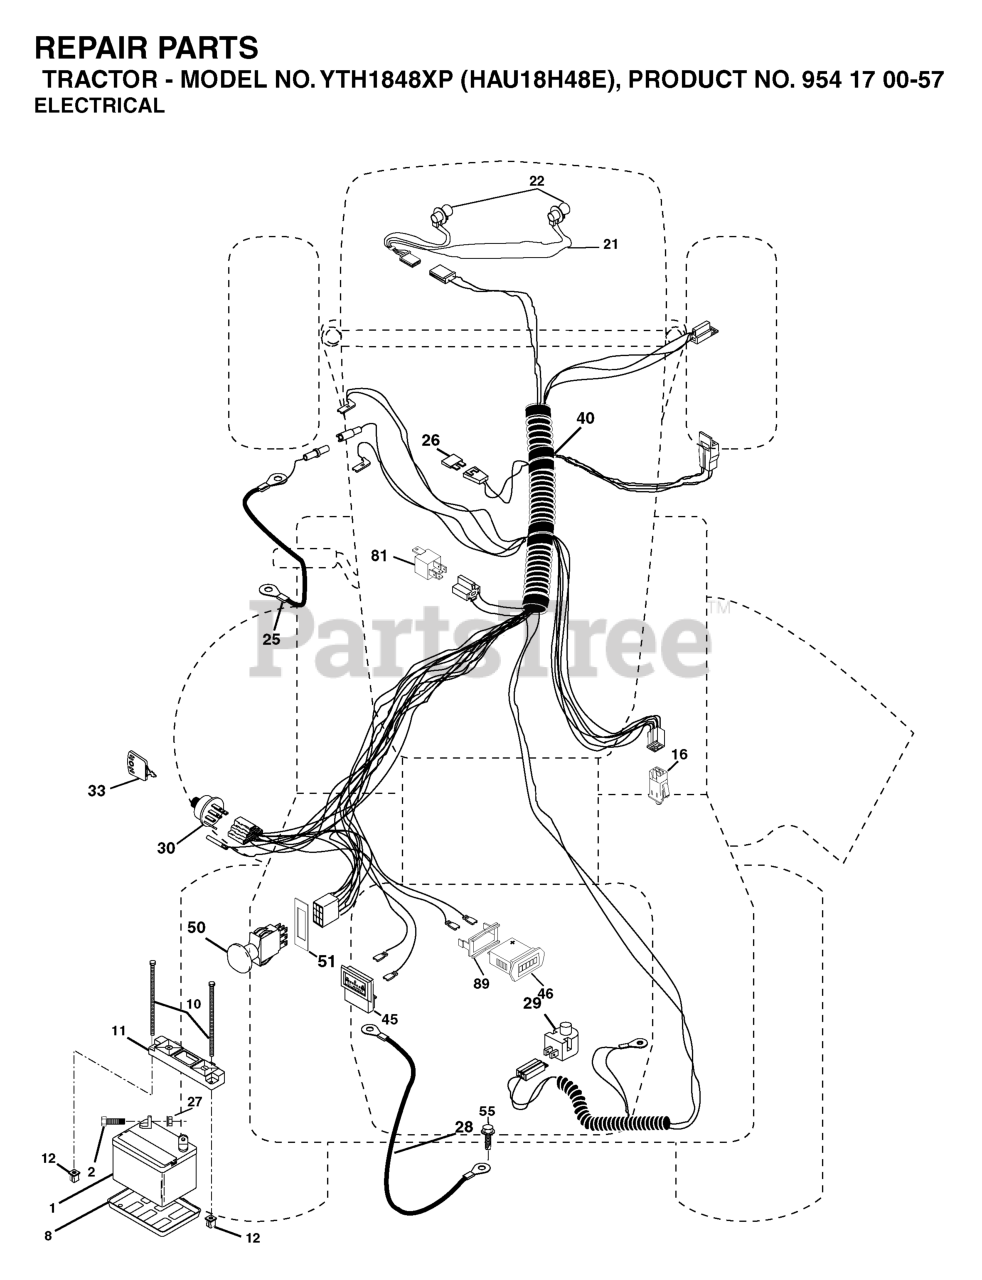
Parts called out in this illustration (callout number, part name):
1	BATTERY 12V .35 AMP
2	BOLT.HEX.1/4.X.3/4.DICHROMATE
8	BATTERY TRAY T
10	BOLT 1/4-20 X 7.5
11	BATTERY HOLDDOWN FRONT MOUNT
12	NUT, PUSH NYLON 1/4" BATTERY
16	SWITCH INTERLOOK PUSH-IN
21	HARNESS.ASM.LIGHT WSL
24	BATTERY CABLE GT
25	CABLE BATTERY 6 GA 22" W/16W
26	FUSE 20AMP
27	NUT
28	CABLE GROUND 6 GA 21" 90T BLK
29	PLUNGER SWITCH (COLOR:OLIVE)
30	IGNITION SWITCH
33	KEY MLD GEN DELTA
40	HARNESS IGN.
41	BOLT
42	TERMINAL COVER
43	SOLENOID
46	HOUR METER
50	RP.PTO.SWITCH.8 TERMINAL.BLACK
51	FRAME RETAINING RING
55	Screw 5/16-18 x 1/2 Hex, Self Tapping 5/16-18 x 1/2
81	RELAY.ASSY.T
89	BRACKET SNAP-IN HOURMETER
